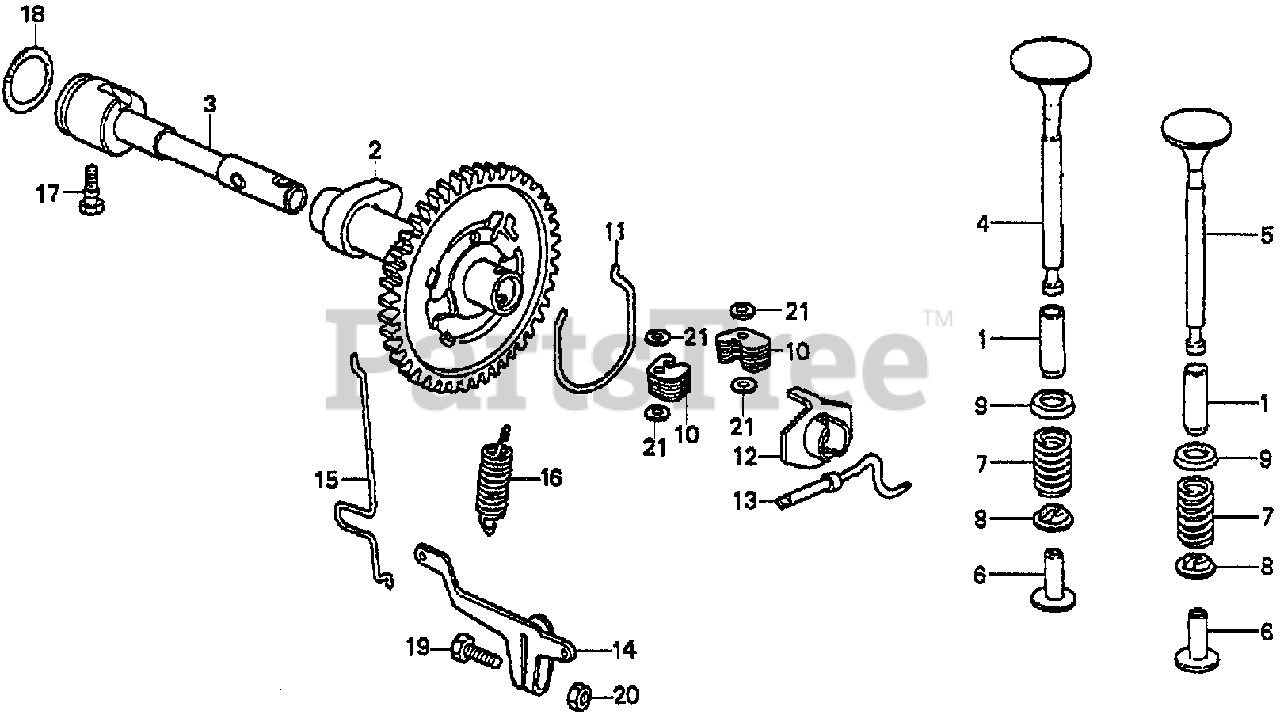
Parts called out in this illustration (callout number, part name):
1	GUIDE, VALVE (OS)
3	CENTER, CAMSHAFT
4	VALVE, IN.
5	VALVE, EX. (NOT AVAILABLE)
6	LIFTER, VALVE
7	SPRING, VALVE (NOT AVAILABLE)
8	RETAINER, VALVE SPRING
9	SEAT, SPRING (NOT AVAILABLE)
10	WEIGHT, GOVERNOR
11	CENTER, GOVERNOR WEIGHT
12	SLIDER, GOVERNOR
13	SHAFT, GOVERNOR ARM (NOT AVAILABLE)
14	ARM, GOVERNOR (NOT AVAILABLE)
15	ROD, GOVERNOR (NOT AVAILABLE)
16	SPRING, GOVERNOR (NOT AVAILABLE)
17	BOLT, CAMSHAFT CENTER STOPPER
18	O-RING (23.5X2.1) (ARAI)
19	BOLT, HEX. (6X16)
20	NUT, HEX. (6MM)
21	WASHER, PLAIN (3MM)
